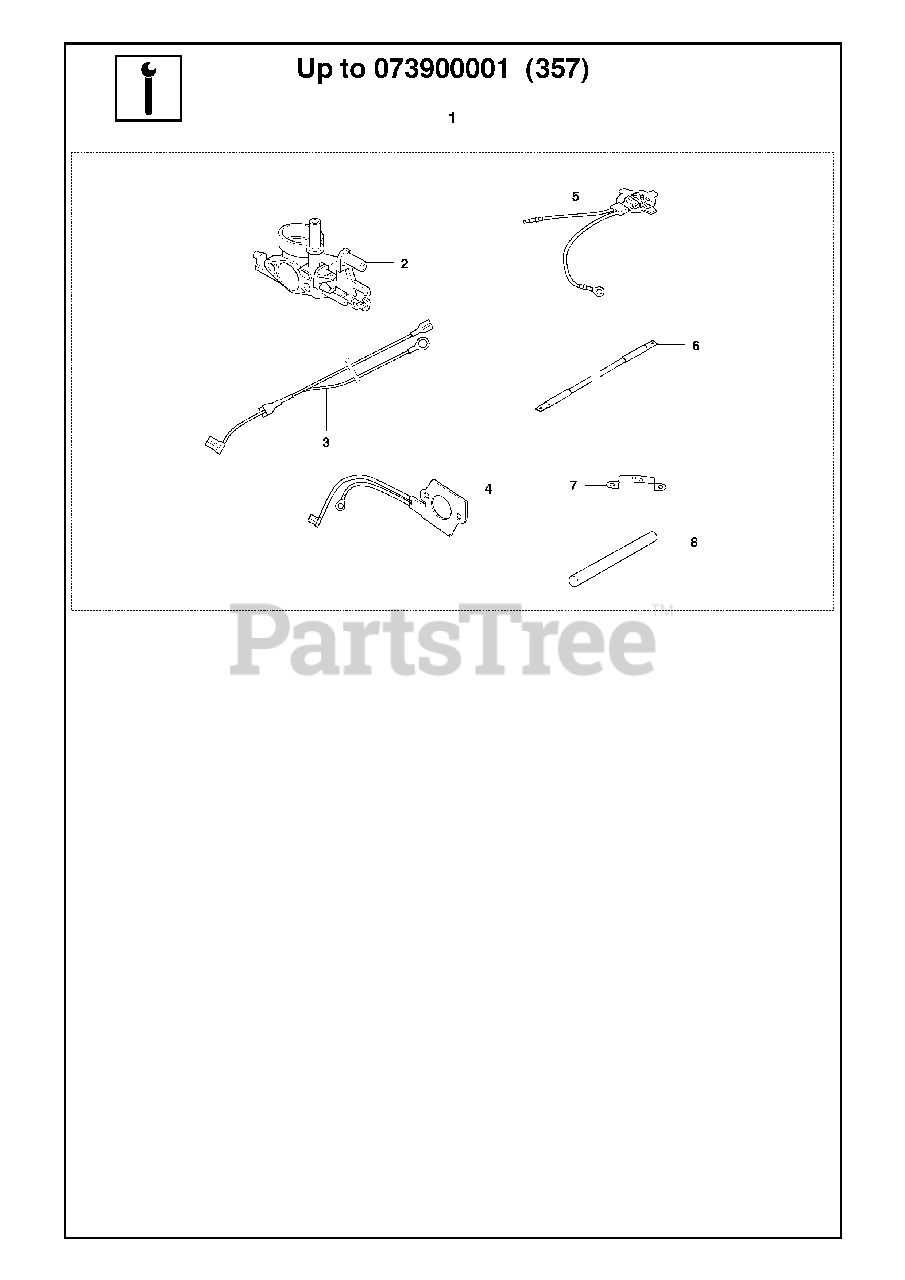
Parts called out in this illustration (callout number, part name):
2	FILTER HOLDER
3	WIRING ASSY
4	Heating Plate
5	THERMOSTAT ASSY
6	WIRING ASSY
8	Cable Cover
